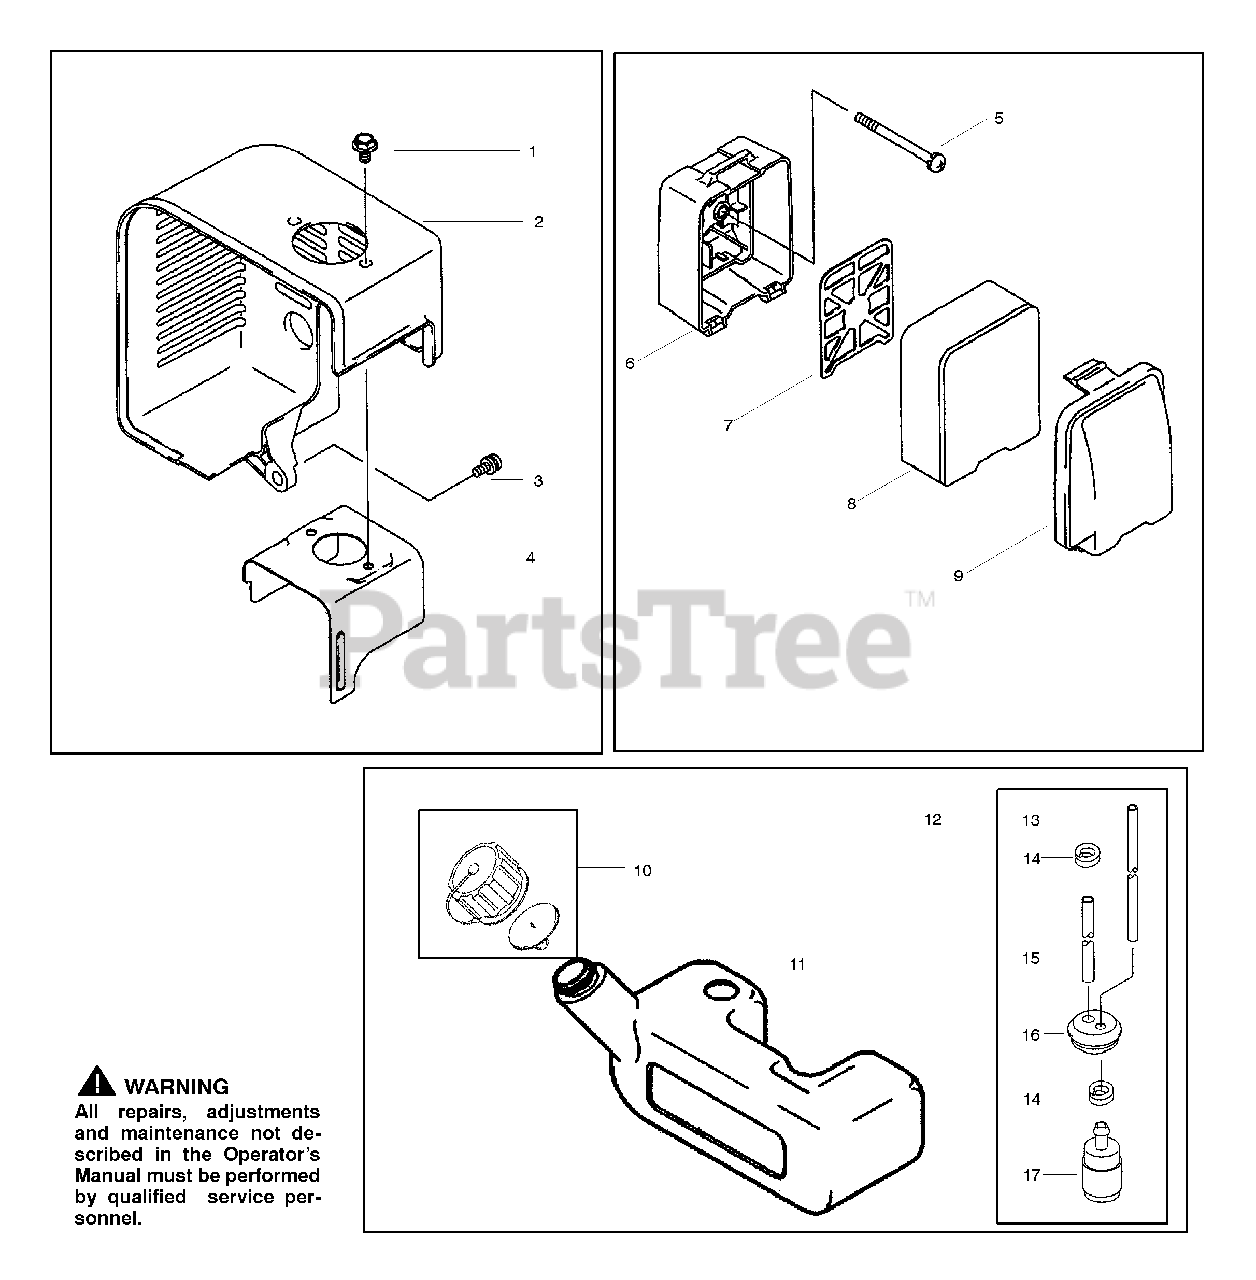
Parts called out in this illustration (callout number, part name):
2	Shroud-Engine
4	Shroud-Engine
6	Assy-Air Filter Case
7	Plate-Air Filter
8	Element-Air Filter
9	Cap-Air Filter
10	Assy-Tank Cap
11	Tank-Fuel
12	Assy-Fuel Pickup
13	Tube 3x5x250
14	Clamp-Fuel Filter
15	Tube 3x6x130
16	Grommet-Tank
17	Filter-Fuel
